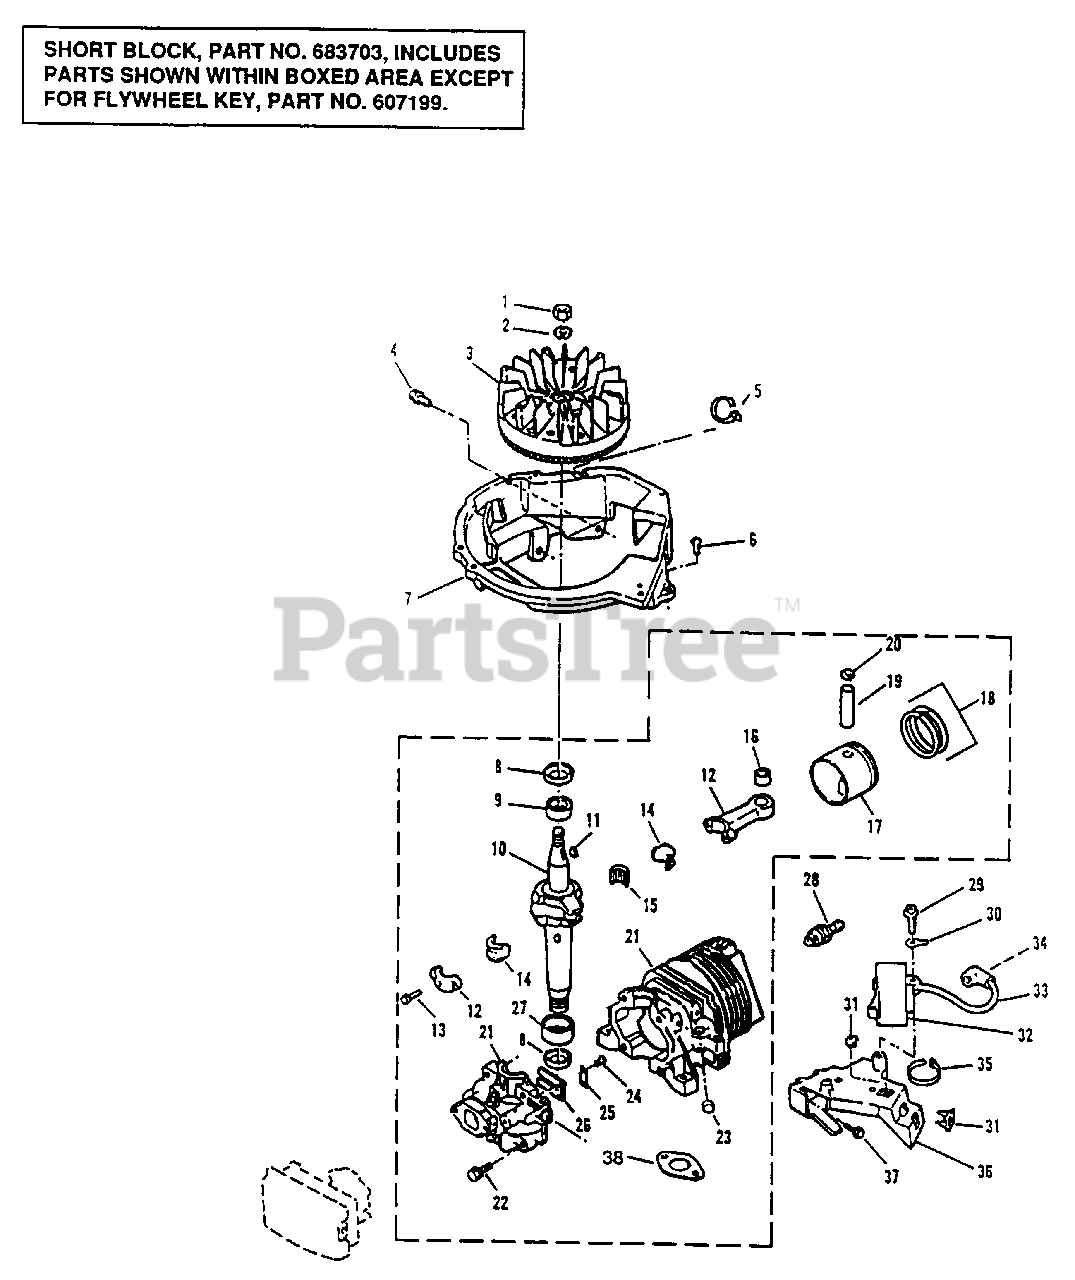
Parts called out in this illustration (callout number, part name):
1	Nut-Flywheel
2	Lockwasher
3	Flywheel
4	Screw
5	Tie Strap
6	Screw-Shd. Base To C.D. Brkt.
7	Base-Shroud
8	Oil Seal
9	Bearing-Upper
10	Crankshaft
11	Key-Flywheel
12	Connecting Rod Assy (Inc. 13-16)
13	Screw-Cap
14	Liner Split
15	Needle Bearing Set
16	Bearing Assembly
17	Piston & Ring Set (Inc. 18-20)
18	Ring Set
19	Wrist Pin
20	Retaining Ring
21	Cylinder & Crankcase Cover Asy. (Inc. 22-26)
22	Screw-Cover To Crankcase
23	Plug-Intake
24	Screw-Reed To Crankcase Cover
25	Plate-Reed Hold Down
26	Reed
27	Bearing-Lower
28	Spark Plug
29	Screw-C.D. Mounting
30	Terminal-Ground Lead
31	Grommet-C.D. Bracket
32	C.D. Ignition Module & Lead Asy (Inc. 33-34)
33	High Tension Lead & Cvr (Inc. 34)
34	Cover & Terminal Assembly
35	Tie Strap
36	Bracket-Ignition Mounting
37	Screw
38	Exhaust Gasket
